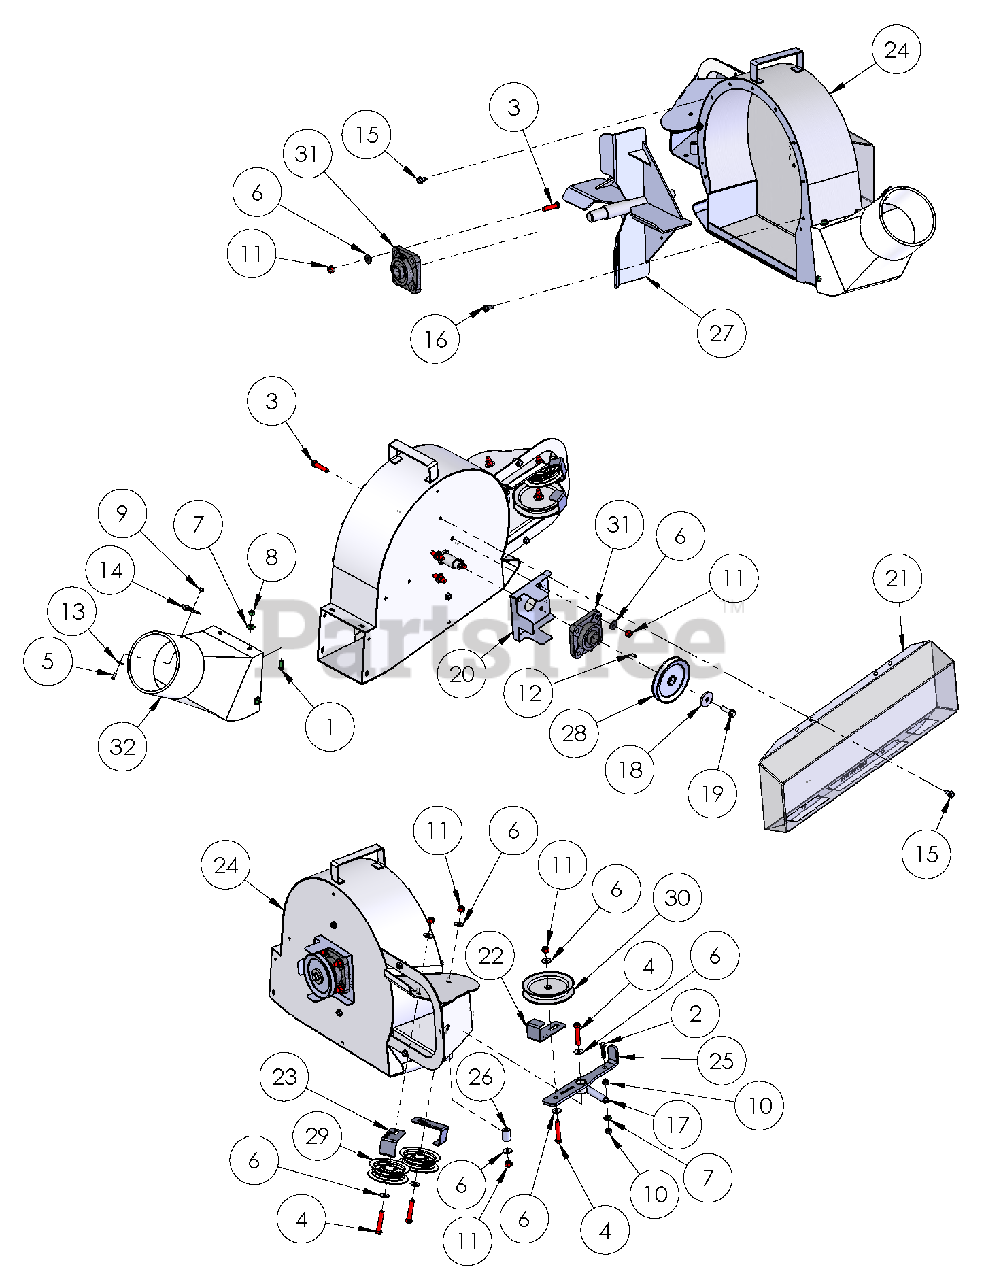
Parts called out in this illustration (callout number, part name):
1	@BLT-HEX .25-20X.75 GR5 YWZC
2	@BLT-HEX .31-18X1.25 GR5 YWZC
3	@BLT-HEX .38-16X1.50 GR5 YWZC
4	@BLT-HEX .38-16X2.00 GR5 YWZC
5	@SCR-MCH 10-24X.50 HWH YWZC
6	@WSHR-FL-STL.344X.688X.065YWZC
7	@WSHR-FL-STL.281X.62X.065 YWZC
8	@NUT-LK-NYL .250-20 YWZC
9	@NUT-LK-NYL 10-24 W/INSRT YWZC
10	@NUT-LK-NYL-FLG .31-18 YWZC
11	@NUT-LK-NYL-FLG .38-16 YWZC
12	KEY 3/16 SQ X .50
13	#10 FENDER WASHER
14	SPRING CLIP
15	5/16 X 5/8" SELF TAP SCREW
16	SELF-TAPPING SCREW 5/16 - .750
17	BELT DRIVE TENSION SPRING
18	FLAT WASHER, .39 ID X 1.5 OD
19	CAP SCREW SERRATED 3/8-16X1.25
20	DRIVEN BELT GUIDE
21	PULLEY / BELT COVER
22	LARGE IDLER BELT GUIDE
23	BELT GUIDE (SMALL IDLER)
24	VERTICAL BLOWER HOUSING
25	IDLER W/A
26	IDLER BUSHING
27	18" BENT BLADE IMPELLER
28	PULLEY, 4 1/2" A, 3/4" ID
29	IDLER PULLEY, 3" HIGH FL 3/8ID
30	5" 'V' GROOVE IDLER
31	SQT PILLOWBLOCK BRG 1.0" I.D.
32	TRANSITION CHUTE - REVISED
